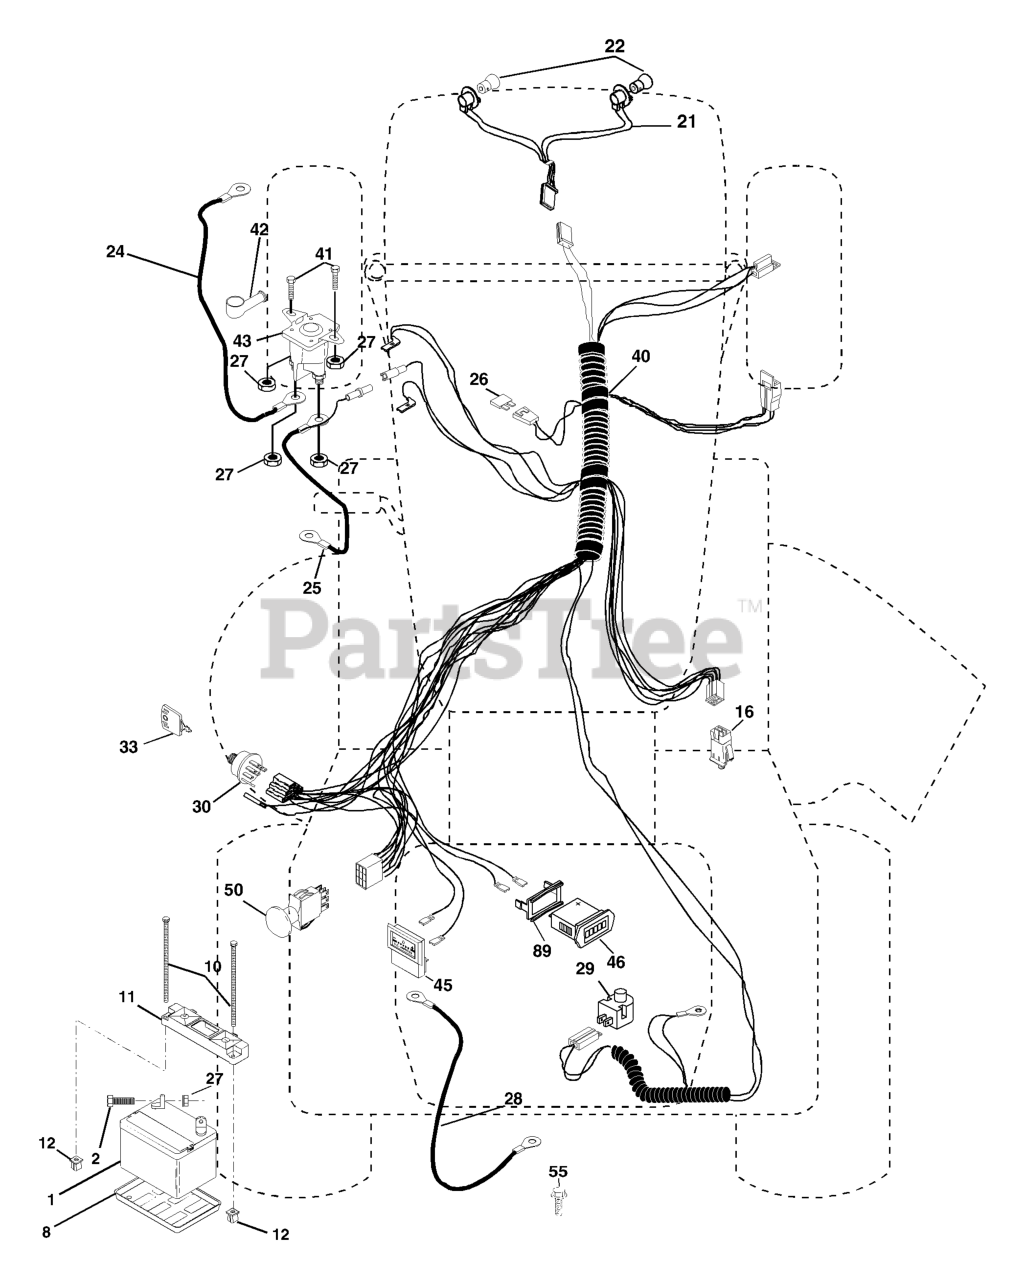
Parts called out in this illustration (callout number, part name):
1	BATTERY 12V .35 AMP
2	BOLT.HEX.1/4.X.3/4.DICHROMATE
8	BATTERY TRAY T
10	BOLT 1/4-20 X 7.5
11	BATTERY HOLDDOWN FRONT MOUNT
12	NUT, PUSH NYLON 1/4" BATTERY
16	SWITCH INTERLOOK PUSH-IN
21	HARNESS ASSY LIGHT
24	BATTERY CABLE GT
25	CABLE BATTERY 6 GA 22" W/16W
26	FUSE 20AMP
27	NUT
28	CABLE GROUND 6 GA 21" 90T BLK
29	RP.SWITCH.PLUNGER.NC.GRAY
30	IGNITION SWITCH
33	KEY MLD GEN DELTA
40	HARNESS.IGNITION
41	BOLT
42	TERMINAL COVER
43	SOLENOID
46	HOUR METER
50	RP.PTO.SWITCH.8 TERMINAL.BLACK
55	Screw 5/16-18 x 1/2
89	BRACKET SNAP-IN HOURMETER
